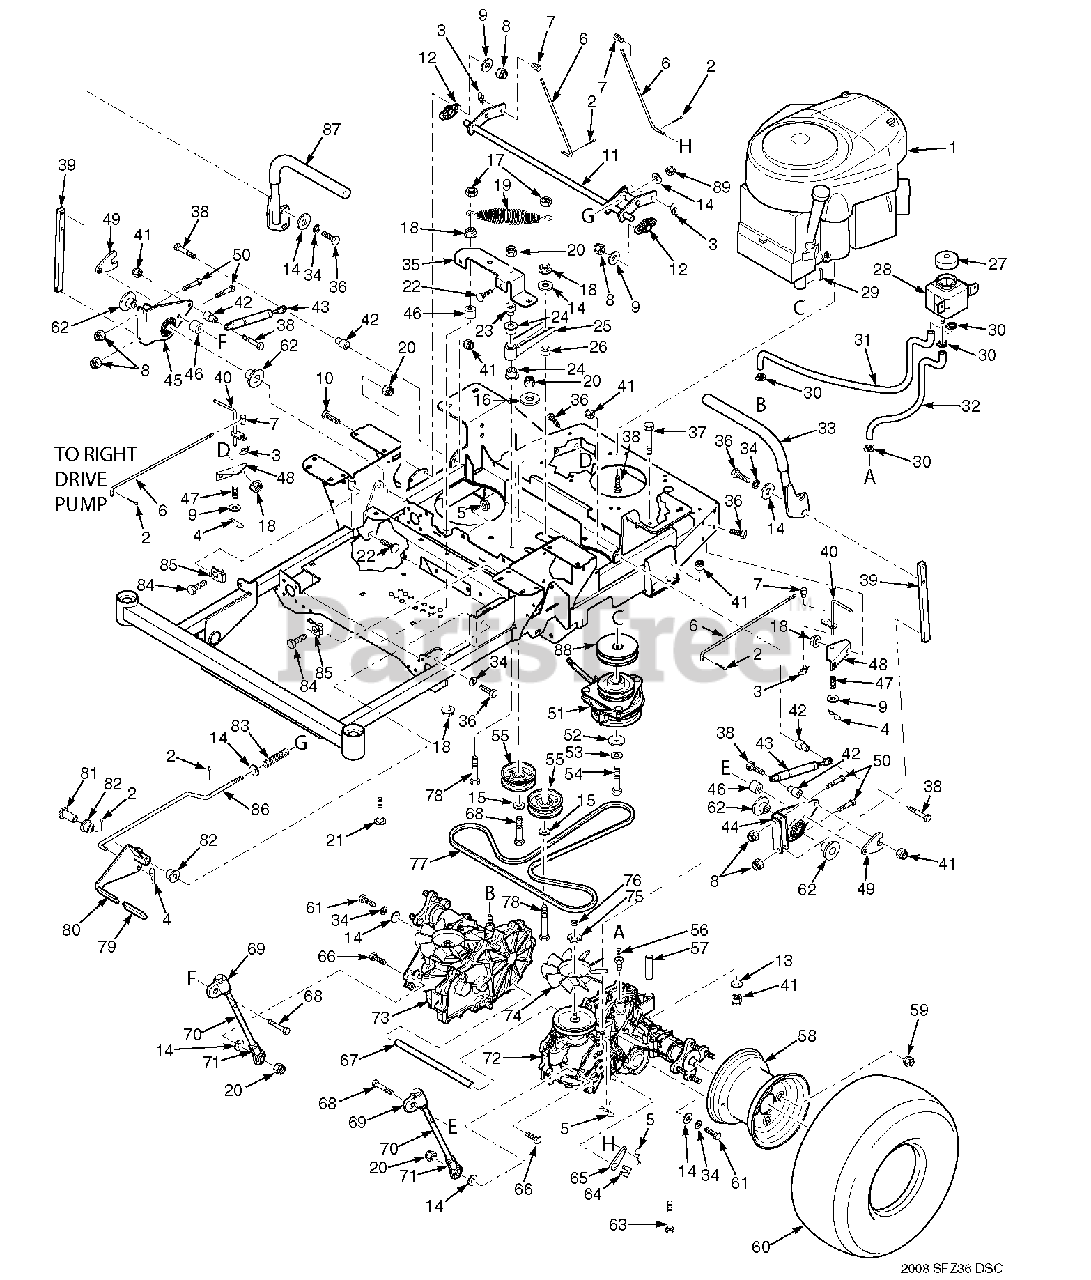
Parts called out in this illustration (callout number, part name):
1	Engine
2	Cotter Pin, 3/32 x 1"
3	Pin, Rue Cotter 3/8" Dia.
4	Hair Pin, .080 x 1.19"
5	Nut, Serrated Flange 5/16-18
6	Rod, Brake Adjustment
7	Joint, Swivel
8	Nut, Elastic Stop 1/4-20
9	Flatwasher, 1/4-.312 x .750 x .065
10	Bolt, Serrated Flange 1/4-20 x 1-1/4"
11	Weldment, Brake Lever
12	Bearing
13	Flatwasher, 5/16-.375 x .875 x .083
14	Flatwasher, 3/8-.391 x .938 x .105
15	Flatwasher, 3/8-.391 x .938 x .105 HD
16	Flatwasher, 3/8-.406 x 1.5 x 7 GA.
17	Nut, Center Lock 3/8-16
18	Nut, Serrated Flange 3/8-16
19	Spring, Transmission Idler
20	Nut, Elastic Stop 3/8-16
21	Bolt, Carriage 3/8-16 x 2"
22	Bolt, Carriage 5/16-18 x 3/4"
23	Shaft Pivot, Idler Arm
24	Bearing
25	Transmission Idler Arm Assembly
26	Spacer, Idler Pulley
28	Reservoir Assembly
29	Key, 1/4 x 1/4 x 1-3/4"
30	Clamp, 0.87" Max Dia.
31	Hose, RH Transmission
32	Hose, LH Transmission
33	Handle Bar Assembly, w/Grip
34	Lockwasher, 3/8" Spring
35	Support, Idler Arm
36	Bolt, Hex Head 3/8-16 x 1"
37	Bolt, Hex Head 5/16-18 x 6"
38	Bolt, Hex Head 5/16-18 x 1-1/2"
39	Bar, Control Lever
40	Dump Valve Lever
41	Nut, Elastic Stop 5/16-18
42	Spacer, Pump Dampener
43	Dampener
44	Control Link, LH
45	Control Link, RH
46	Spacer
47	Spring
48	Bracket, Dump Mounting
49	Nut, Control Linkage
50	Bolt, Hex Head 1/4-20 x 1-1/2"
51	Electric Clutch Assembly
52	Flatwasher, 7/16-.469 x 1.75 x .25
53	Lockwasher, 7/16" spring
54	Bolt, Hex Head 7/16-20 x 2-1/4" Patch
55	Pulley, 3-1/2" Dia.
56	Fitting, Transmission
57	Spacer, Axle
58	Rim w/Valve Stem
59	Wheel Nut, 1/2-20
60	Wheel Assembly
61	Bolt, Hex Head 3/8-16 x 2-1/4"
62	Spacer, Linkage
63	Bolt, Hex Head 5/16-18 x 2-1/4"
64	Clip, Brake Lever
65	Lever, Brake
66	Bolt, Hex Head 3/8-16 x 1-1/4"
67	Spacer, Axle
68	Bolt, Hex Head 3/8-16 x 2"
69	Rod End, Adjustable
70	Linkage, Pump
71	Stake, Rod End Assembly
72	Transaxle Assy.
73	Transaxle Assy.
74	Fan
75	Fan Washer
76	Fan Nut
77	Belt, TRansmission Drive
78	Bolt, Hex Head 3/8-16 x 3"
79	Grip, Brake Handle
80	Brake Handle Assembly
81	Spacer, Brake Handle
82	Bearing
83	Spring, Brake
84	Bolt, Hex Head 3/8-16 x 1-1/4" Special Lock
85	U-Nut, 3/8-16
86	Rod, Brake Linkage
87	Handle Bar w/Grip
88	Pulley, 4-1/2" Dia. 1" Bore
89	Nut, Elastic Stop 3/8-24 Gr. 8
